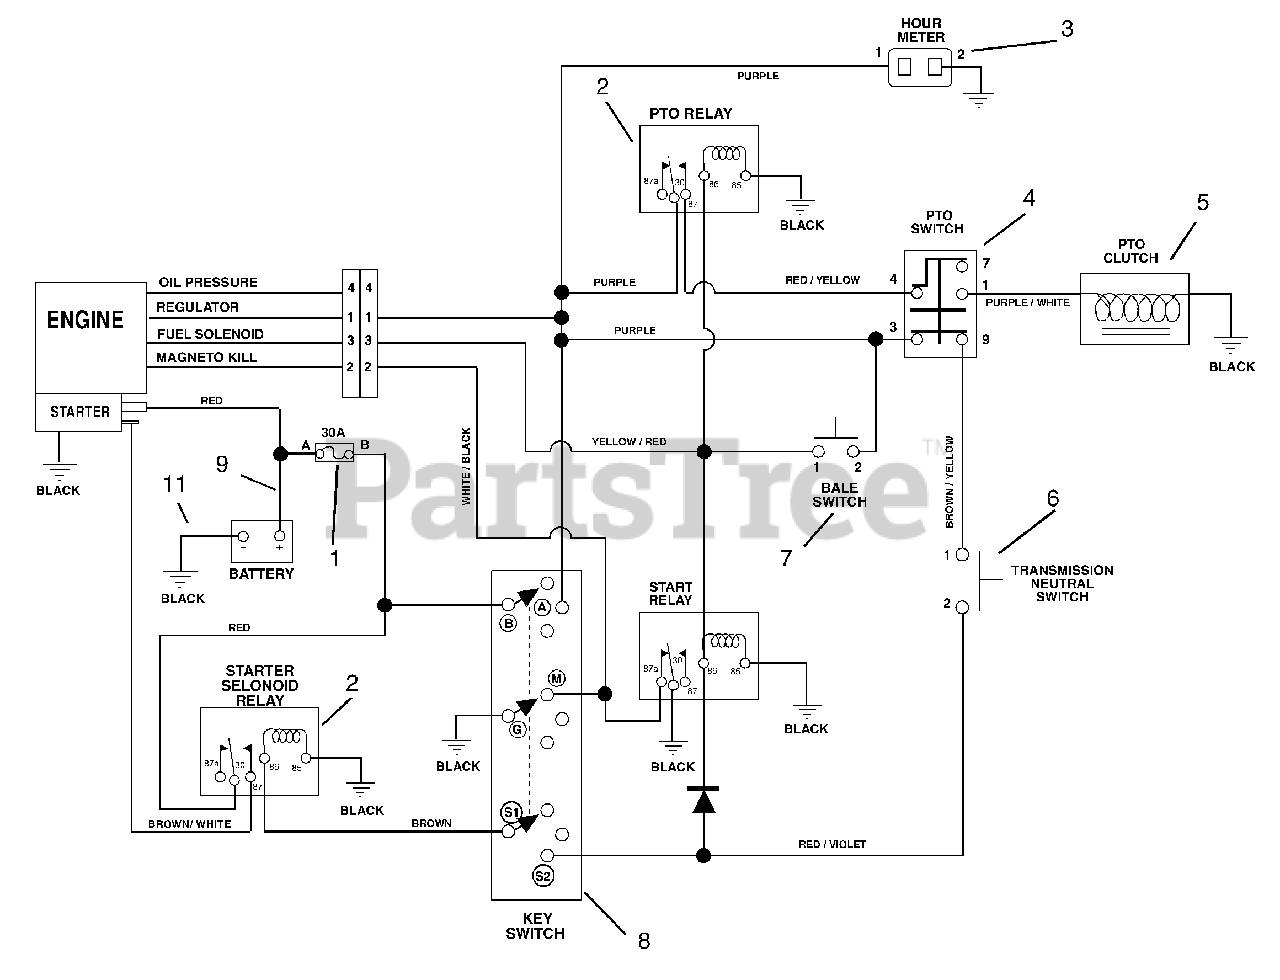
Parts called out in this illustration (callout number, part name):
2	Relay
3	Hour Meter
4	Switch-Clutch with Retainer
5	Clutch-Electric
6	Transmission-Switch Neutral (N.C.)
7	Switch-Bale
8	Key Switch
9	Cable-Positive
10	Cable-Battery to Starter
11	Cable-Negative Battery
